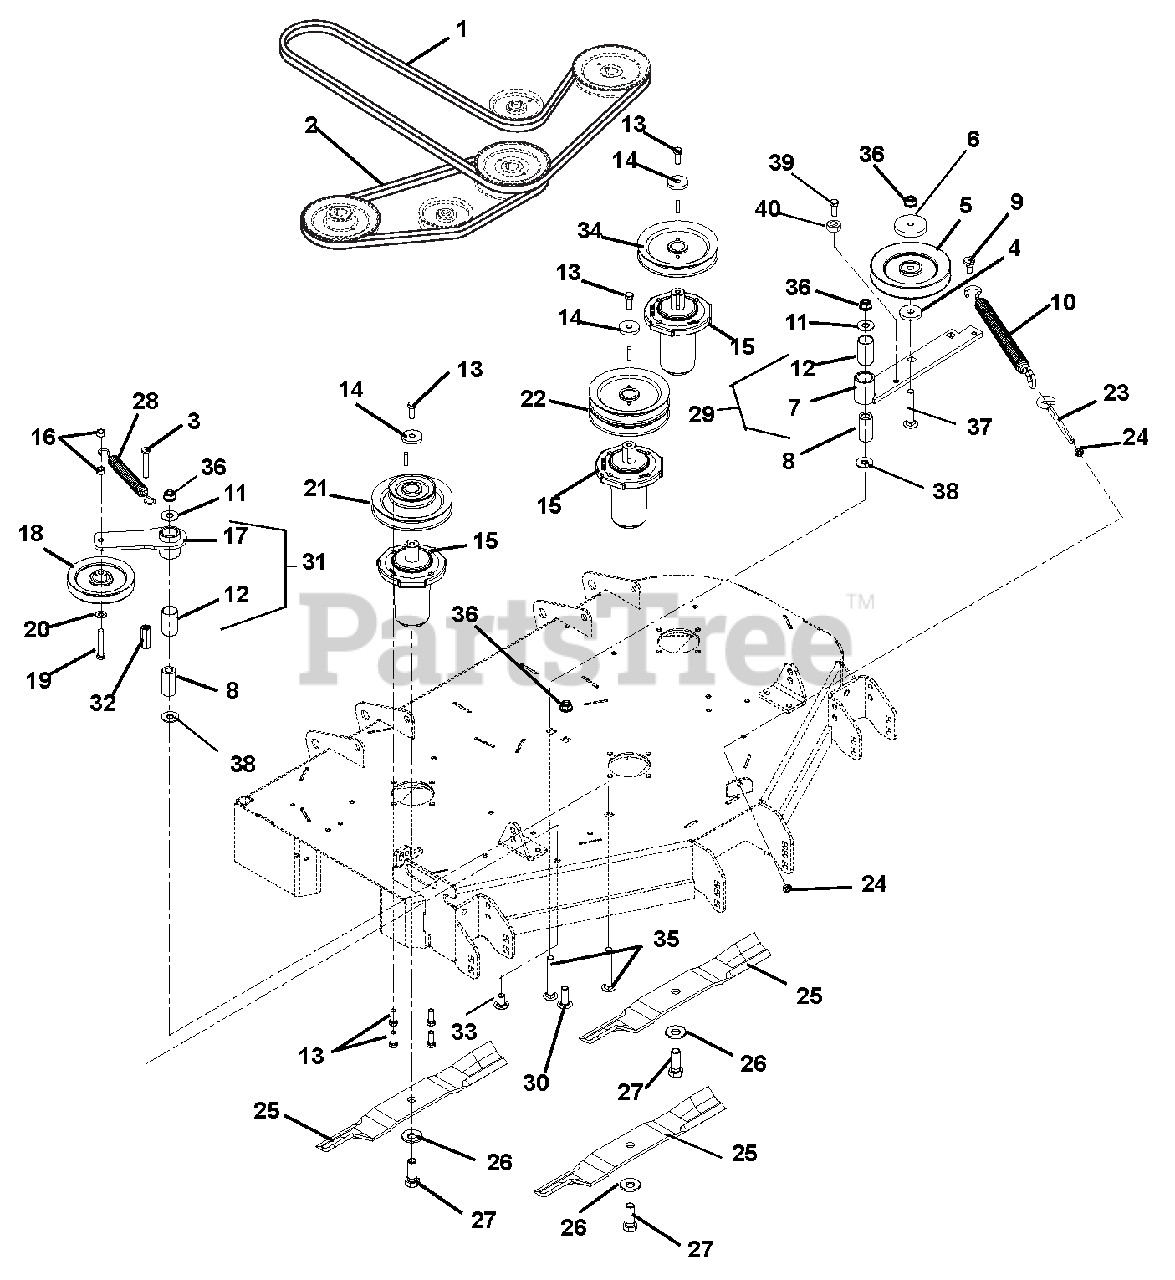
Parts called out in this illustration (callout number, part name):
1	HEX BELT, BB-WRAPPED
2	V-BELT, B-COGGED
3	@BLT-HEX .38-16X1.50 GR5 YWZC
4	BSHG, SPCR .502X.997X.50 PM
5	SHV, .50"ID X 6.00"OD V-IDLER
6	CAP, IDLER BEARING SEALING
7	WMT, IDLER ARM
8	BSHG, SPCR .502X.997X2.03 PM
9	BLT,SHLDR EP .38-16X.30 HEX YZ
10	SPRING, EXTENSION
11	@WSHR-FL-STL.563X1.38X.109YWZC
12	BSHG, 1.00 X 1.125 X 1.937
13	BLT-HEX .38-16X1.0 GR8 YZ EP30
14	WSHR,FLT STL.406X1.50X.245YWZC
15	ASSEMBLY, SPINDLE
16	@NUT-LK-CTR .38-16 YWZC
17	WMT, IDLER ARM
18	SHV, .38"ID X 5.00"OD V-IDLER
19	@BLT-HEX .38-16X2.25 GR5 YWZC
20	@WSHR-FL-STL.406X.812X.065 YWZ
21	PULLEY, DBL-1"IDX5.75"&3.50"OD
22	PULLEY, DOUBLE-1"ID X 5.75"OD
23	BOLT, .38-16X4.50 .62 DIA EYE
24	NUT-HEX-JAM .375-16 YWZC
25	BLADE, 16.19" MOWER (HI-LIFT)
26	WSHR-BLVL .669X1.535X.138
27	BLT-HEX .62-18X1.75 GR8 YWZC
28	SPRING, EXTENSION
29	ASM, IDLER PIVOT ARM (PTO)
30	BLT-RDHDSHSQNKFT.50-13X1.50 G5
31	ASM, IDLER ARM (DECK)
32	NUT COUPLING .375-16X1.75
33	@BLT-RDHDSHSQNK.38-16X1.0 G5YZ
34	PULLEY, V-1" ID X 5.75" OD
35	@BLT-RDHDSQNK .50-13X3.50 G5YZ
36	@NUT-LK-NYL-FLG .50-13 YWZC
37	@BLT-RDHDSQNK .50-13X3.00 G5YZ
38	WSHR-FLT .640X1.75X.250
39	@BLT-HEX .38-16X2.75 GR5 YWZC
40	@NUT-HEX .38-16 YWZC
